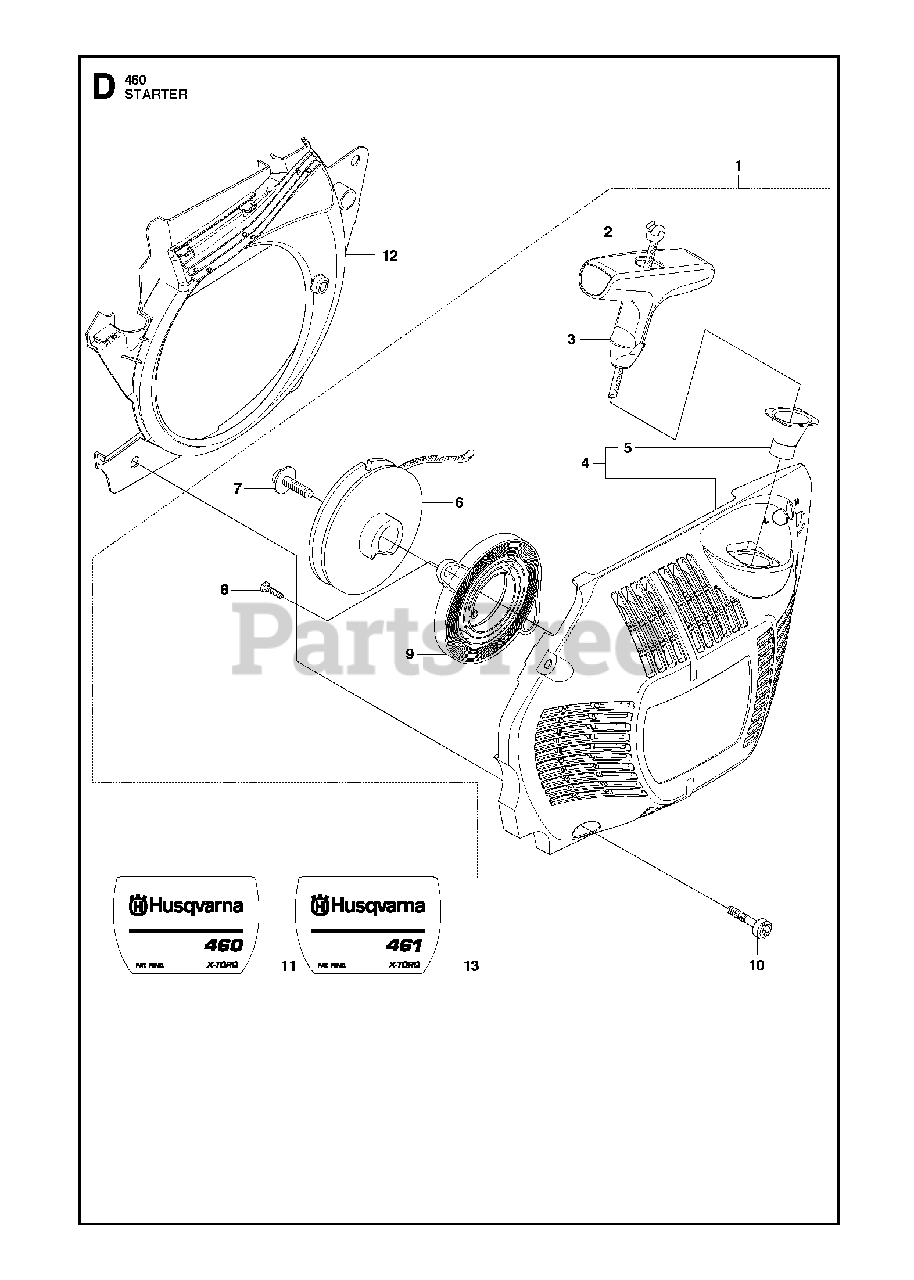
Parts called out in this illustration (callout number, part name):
1	STARTER HOUSING CPL.
2	STARTER ROPE
3	HANDLE
4	STARTER HOUSING
5	SLEEVE
6	PULLEY
7	SCREW
8	SCREW
9	RETURN SPRING
12	AIR CONDUCTOR
